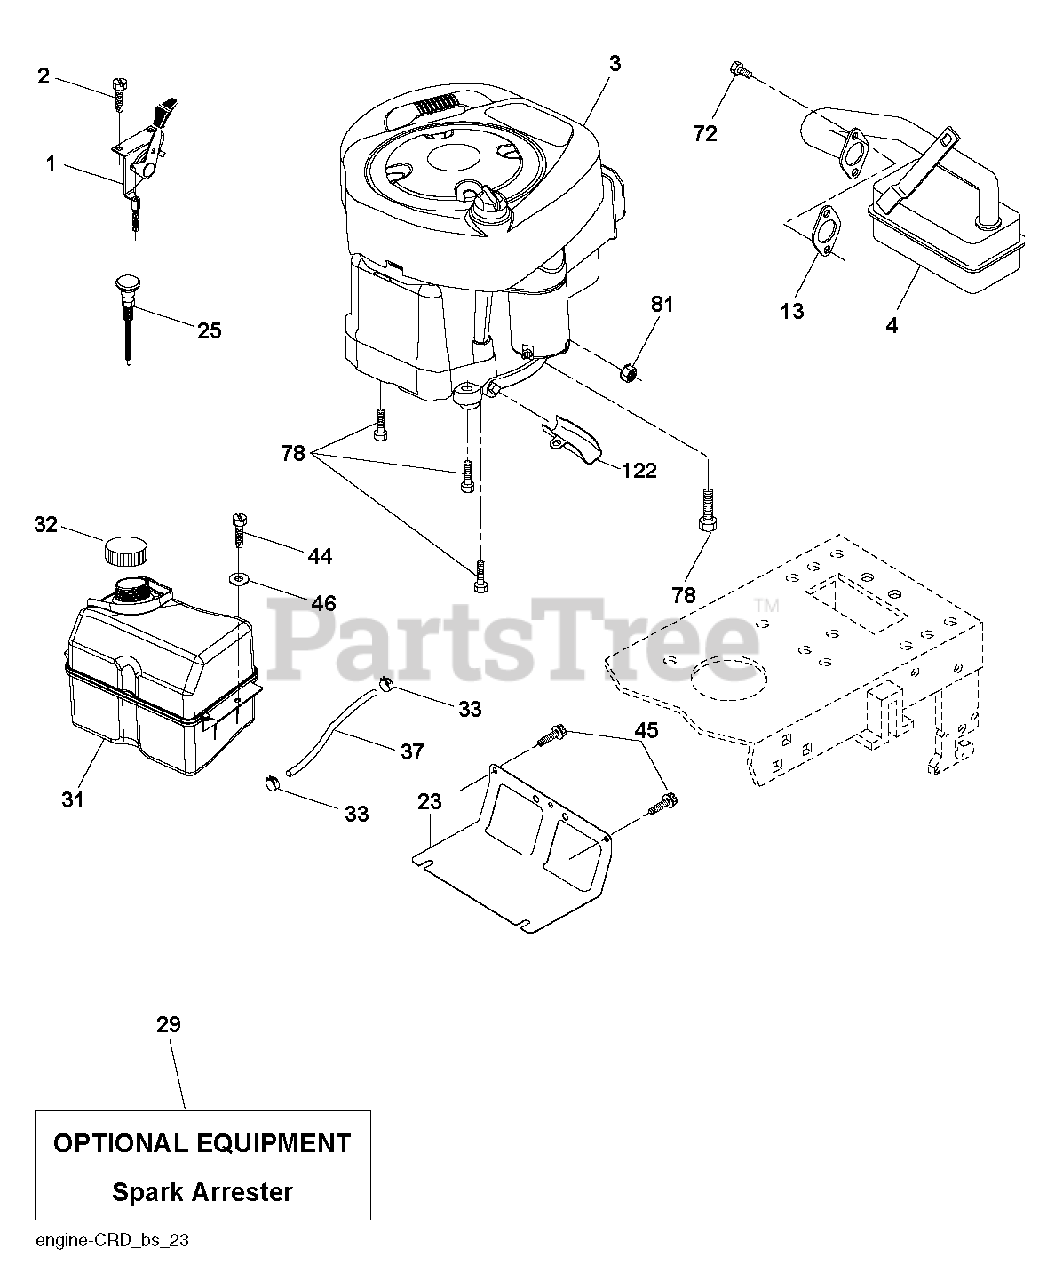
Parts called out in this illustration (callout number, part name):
1	CONTROL TH/CH FLAG
2	SCREW
13	REPL BY 532 27 22-93
23	SHEILD.BROWNING.DBR.GUARD
29	ARRESTER SPARK (OPTIONAL)
32	CAP ASM.FUEL.2.25"FR.
33	HOSE CLAMP
37	LINE.FUEL.20
44	SCREW HEXWSHR 1/4-20X3/4
45	SCREW, 3/8-16X3/4
72	SCREW.SOCKET HD.5/16-1
78	SCREW.3/8-16
81	NUT
122	EXTENSION DRAIN OIL
